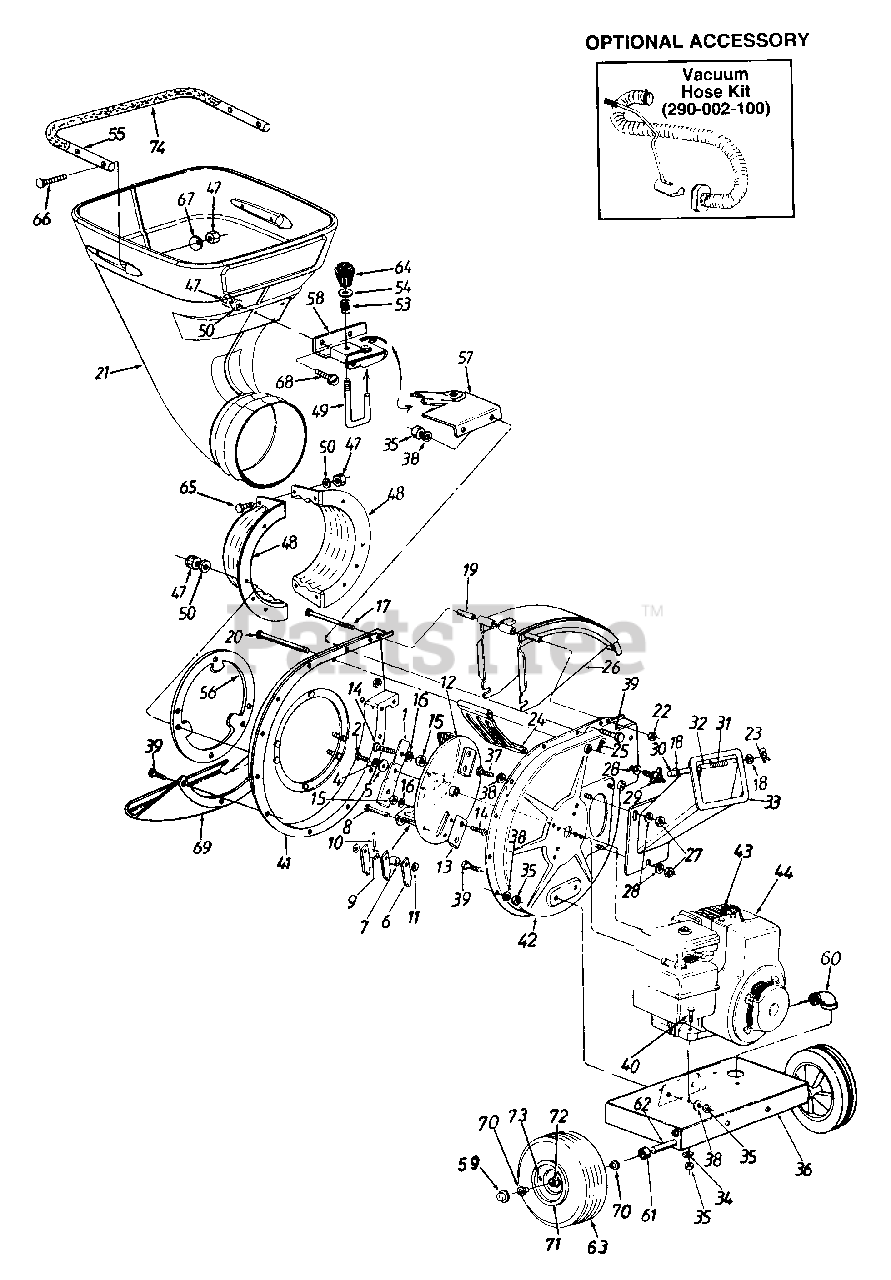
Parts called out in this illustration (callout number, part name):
1	Blade
2	Hex Patch Bolt 3/8-24 x 2.25" Lg.
4	L-Wash. 3/8" I.D. H.D.
5	FI-Wash..406" I.D. x 1.25" O.D. Hdn.
6	Flail
7	Flail Spacer
8	Clevis Pin .496" Dia.
9	Flail Spacer w/.160" Dia. Hole
10	Spring Roll Pin 1.125" Lg.
11	FI-Wash..531" I.D. x.94" O.D.
12	Impeller Ass'y. Comp.
13	Chipper Blade
14	Flat Hd. Scr. 5/16-24 x .75" Lg.
15	Hex Top L-Nut 5/16-24 (Gr. 5)
16	L-Wash. 5/16" I.D.
17	Hex Bolt 1/4-20 x 3.75" Lg.
18	FI-Wash..281" I.D. x .50" O.D.
19	Chute Hinge Spacer 1.66" Lg.
20	Clevis Pin .5" Dia. x 4.62" Lg.
21	Rotating Hopper
22	Hex Ctr. L-Nut 1/4-20 Thd.
23	Cotter Pin
25	Internal Cotter Pin 3/8" Dia.
27	Hex Nut 5/16-18 Thd. (Gr. 5)
28	Bell-Wash..345" I.D. x .88"
29	Hand Knob
30	Chipper Door Rod
31	Torsion Spring 1.14" Lg.
35	Hex Nut 5/16-18 Thd. (Gr. 5)
37	Hex Bolt 5/16-24 x .75" Lg.
38	L-Wash. 5/16" I.D.
39	Hex Bolt 5/16-18 x .75" Lg. (Gr. 5)
40	Hex Bolt 5/16-18 x 1.5" Lg.
44	Engine
47	Elastic Lock Nut 5/16-18 Thd.
48	Hopper Mtg. Collar
49	Locking Pin
50	Fl-Wash. 5/16" I.D.
53	Spring 1.5" Lg
54	FI-Wash..385" I.D x 62" O.D.
60	Drain Elbow
61	Spacer .64" I.D. x .38" Lg.
62	Shredder Axle
64	Knob
65	Hex Bolt 5/16-18 x 1" Lg. (Gr. 5)
66	Curved Carr. Bolt 5/16-18 x 1.25" Lg.
67	Saddle Wash. 32" I.D.
68	Carr. Bolt 5/16-18 x .75" Lg.
70	Flange Bearing .632" I.D.
73	Air Valve
74	Foam Grip
